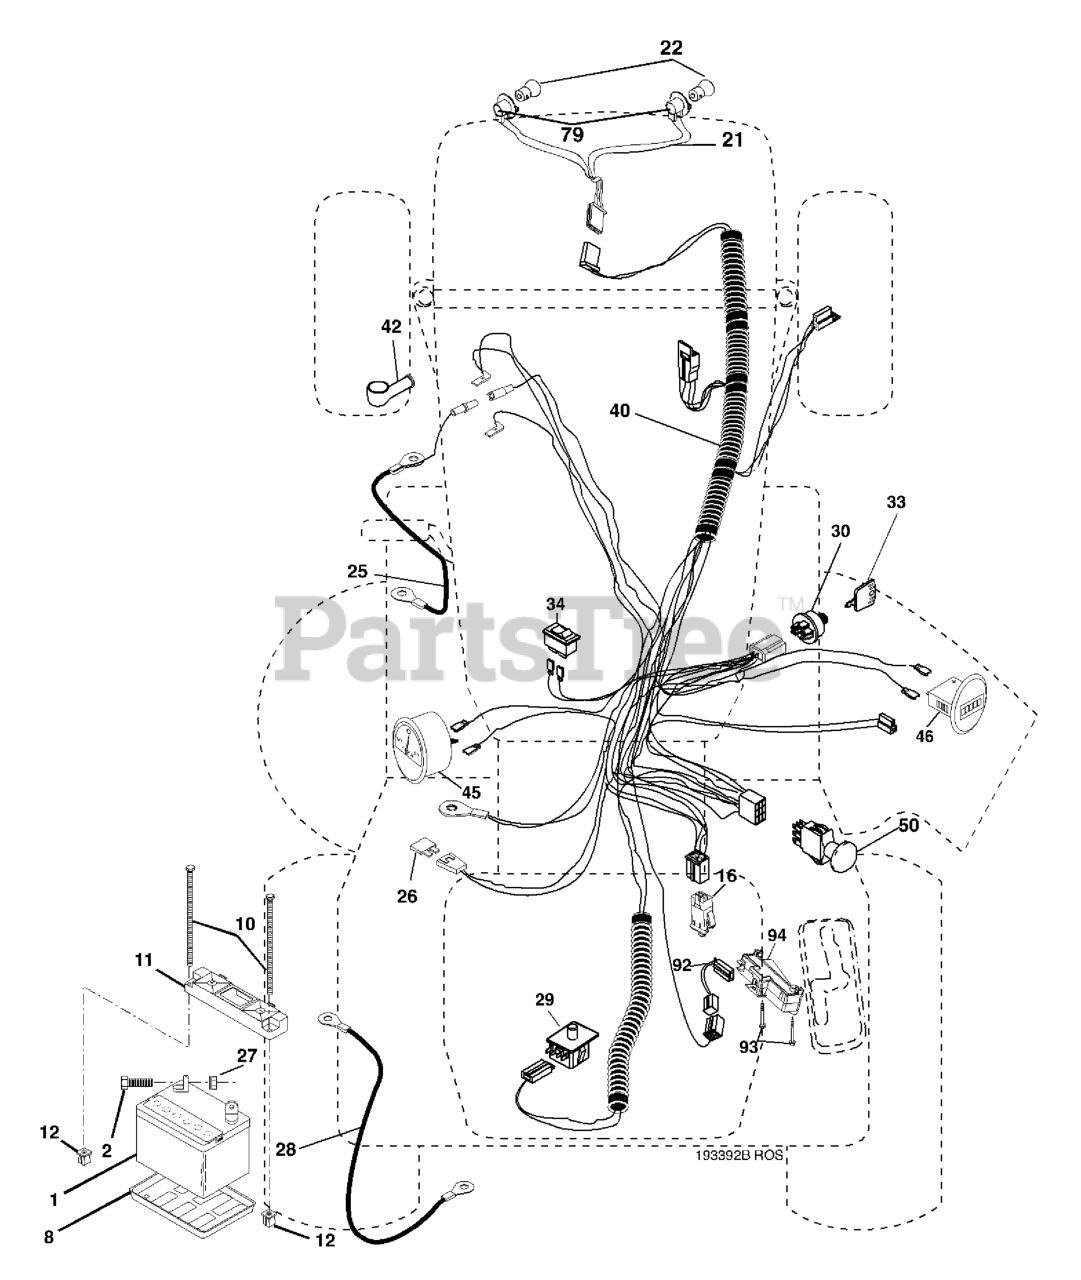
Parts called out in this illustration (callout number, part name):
1	BATTERY 12V .35 AMP
2	BOLT.HEX.1/4.X.3/4.DICHROMATE
8	BATTERY TRAY T
10	BOLT 1/4-20 X 7.5
11	BATTERY HOLDDOWN FRONT MOUNT
12	NUT, PUSH NYLON 1/4" BATTERY
16	SWITCH INTERLOOK PUSH-IN
21	HARNESS.W/LIGHT SOCKET
25	CABLE.4GA.RED.W/16GA.RED.WIRE
27	NUT
28	CABLE, GROUND
29	SWITCH.SEAT.DP W/RAMPS
30	SWITCH.IGN.DELTA.W.LGH.ROS
33	KEY MLD GEN DELTA
40	HARNESS. IGN.VGT.RHD
42	COVER.TERMINAL.RED
45	RP AMMETER.ROUND.SILVER.DELTA
46	RP HOURMETER SNAP-IN
50	RP.PTO.SWITCH.8 TERMINAL.BLACK
79	BULB HOLDER ASM.
92	HARNESS.PIGTAIL.REVERSE.SWITCH
93	SCREW.PLASTITE
94	MODULE.REVERSE.ROS
